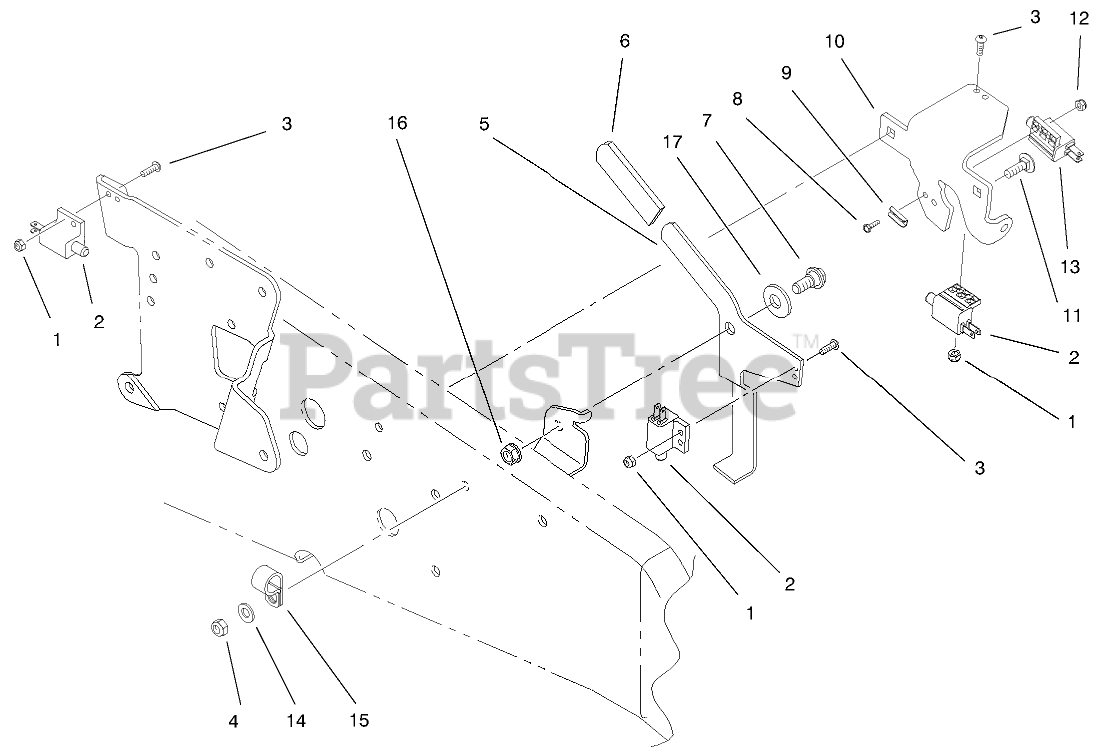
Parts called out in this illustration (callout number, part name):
1	NUT-LOCK, NI
2	SWITCH-POLE, SINGLE
3	SCREW-HSH
4	NUT-LOCK, NI
5	LATCH-BRAKE, PARKING
7	BOLT-SHOULDER
8	SCREW-SHH
9	RETAINER-SCREW
10	BRACKET-SWITCH
11	SCREW-CARR
12	NUT-LOCK
13	SWITCH-POLE, SINGLE
14	WASHER-PLAIN
15	CLAMP - R
17	WASHER
